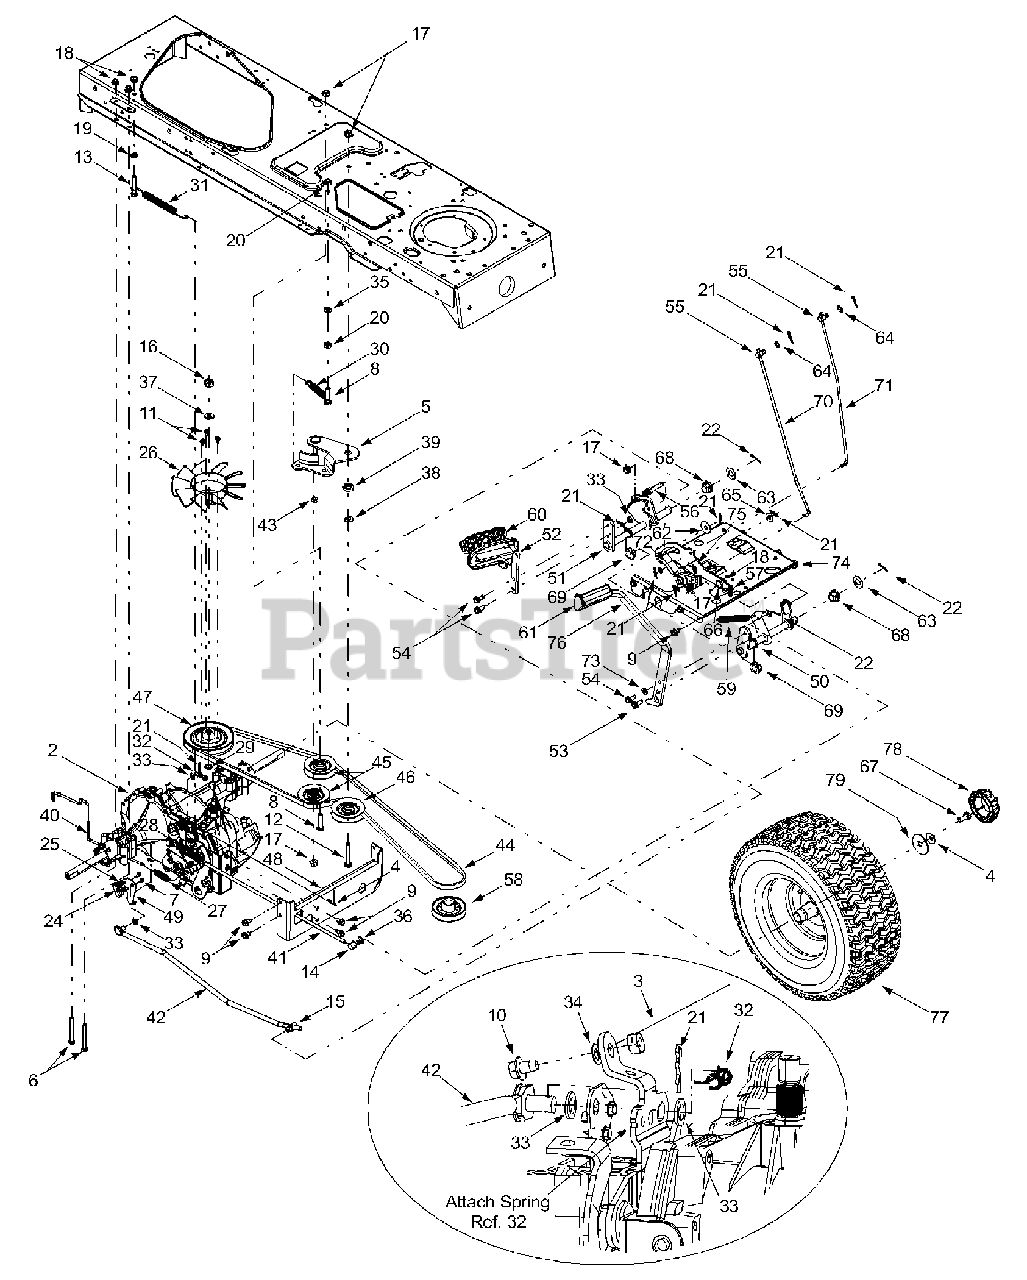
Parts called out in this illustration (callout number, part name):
2	Hydrostatic Transmission
3	Reverse Wire Harness Adapter & Ground
4	Bell Washer, .34 x .872
5	Double Idler Bracket Assembly
6	Hex Cap Screw, 5/16-18 x 2.75
7	Screw, #8-18 x .5
8	Hex Cap Screw, 3/8-16 x 1.5
9	Self-tapping Screw, 5/16-18 x .625
10	Self-tapping Screw, 1/4-20 x .375
11	Screw, #12-24 x .375
12	Hex Cap Screw, 3/8-16 x 2.25
13	Hex Cap Screw, 5/16-18 x 2.0
14	Ferrule, 5/16-18
15	Ferrule, 3/8-24
16	Hex Nut, 1/2-20
17	Flange Lock Nut, 3/8-16
18	Flange Lock Nut, 5/16-18
19	Hex Nut, 5/16-18
20	Hex Nut, 3/8-16
21	Internal Cotter Pin
22	Cotter Pin
23	Cable Tie
24	Short Spring Switch
25	Insulator Nut Plate
26	10-inch Fan
27	Extension Spring, .48 x 2.03
28	Extension Spring, .59 x 4.0
29	Wire Ring
30	Extension Spring, .5 x 3.97
31	Extension Spring, .5 x 7.0
32	Extension Spring, 3/8 x 1.44
33	Flat Washer, .385 x .62 x .063
34	Flat Washer, .281 x .50 x .063
35	Lock Washer, 3/8
36	Flat Washer, .344 x .688 x .065
37	Lock Washer, 1/2
38	Flat Washer, .407 x .812 x .135
39	Shoulder Spacer, .38
40	Hydrostatic Bypass Rod
41	Hydrostatic Brake Rod
42	Hydrostatic Control Rod
43	Spacer, .376 x .625 x .22
44	Drive Belt
45	V-idler Pulley, 3.06
46	Flat Idler Pulley, 2.75
47	Input Pulley, 5.0
50	Brake Control Assembly
51	Drive Control Assembly
52	Hydro Pedal Assembly
53	Self-tapping Screw, 5/16-18 x .875
54	Self-tapping Screw, 5/16-18 x .75
55	Ferrule, 1/4-20
56	Pin, 3/8-16 x 2.43
57	Compression Spring, .405 OD x 1.17
58	Engine Pulley
59	Extension Spring, .50 OD x 6.37
60	Drive Pedal Pad
61	Brake Pedal Pad
62	Flat Washer, .411 x 1.25 x 1.0
63	Flat Washer, .64 x 1.24 x .06
64	Flat Washer, .344 x .062 x .03
65	Flat Washer, .406 x .875 x .105
66	Shoulder Screw, .437 x 1.62
67	Hex Cap Screw, 5/16-24 x .75
68	Hex Flange Bearing
69	Split Hex Flange Bearing
70	Cruise Control Rod
71	Brake Lock Control Rod
72	Cruise Latch
73	Flat Washer, .344 x .750 x .120
75	Drive Lockout Bracket
78	Deluxe Hub Cap
79	Flat Washer, .350 x 1.59 x .062
